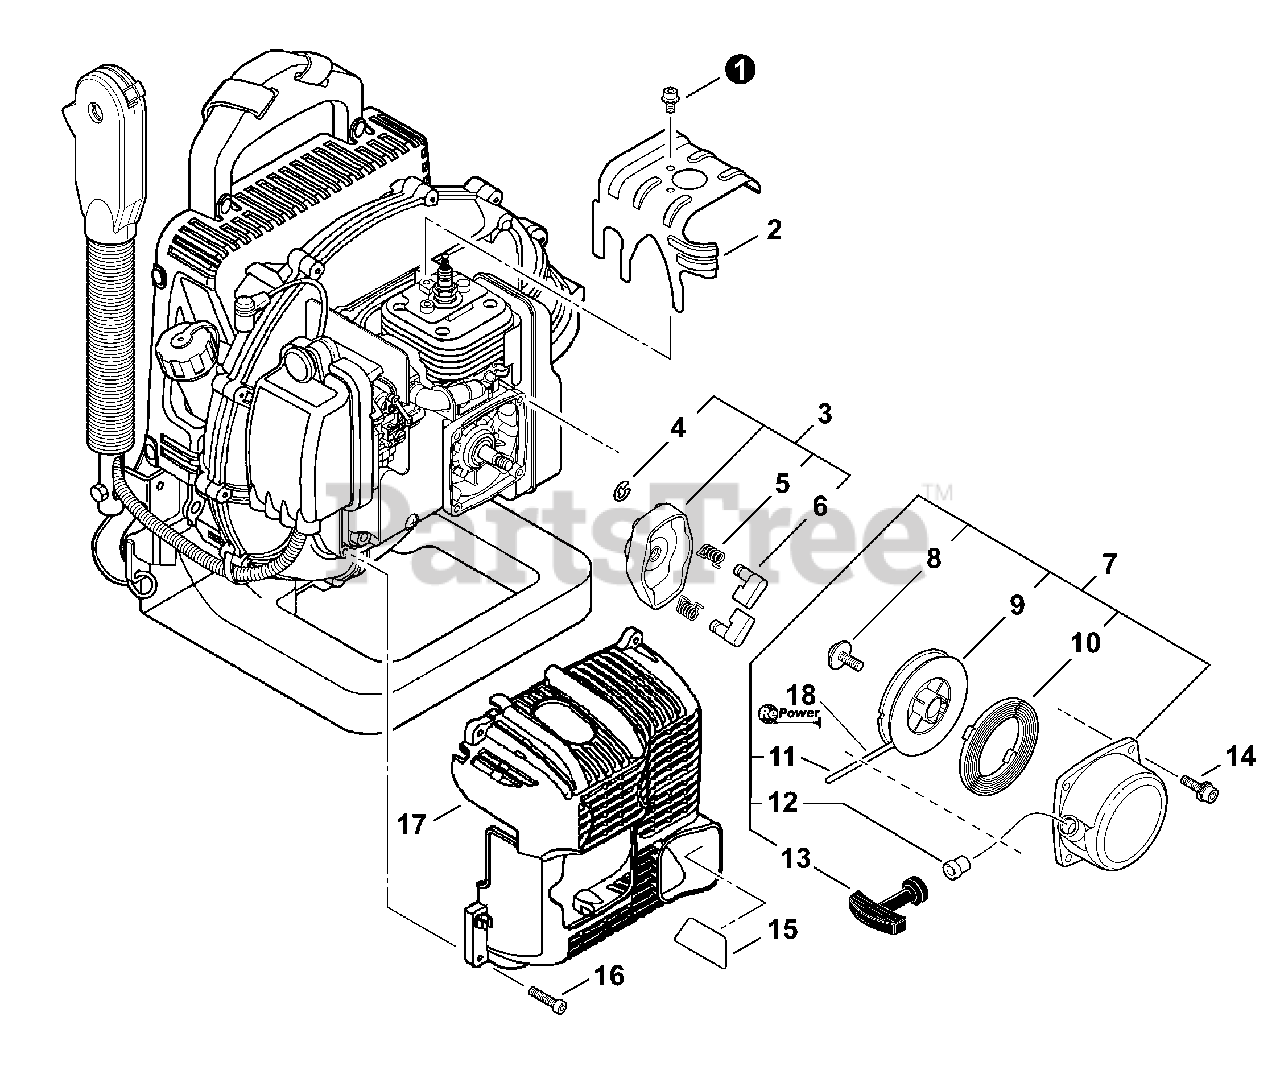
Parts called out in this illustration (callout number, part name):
1	SCREW - 5×8
2	SHIELD, CYLINDER
3	STARTER PAWL ASSY
4	RING, RETAINING - 4
5	SPRING, RETURN
6	PAWL, STARTER
7	STARTER ASSY
9	REEL, ROPE
10	SPRING, REWIND
11	ROPE, STARTER
12	GUIDE, ROPE
13	GRIP, STARTER
14	SCREW - 5×18
15	DEFLECTOR, HEAT
16	SCREW - 5×20 -- TAPPING
17	COVER, ENGINE
18	ROPE, STARTER - REPOWER BULK
